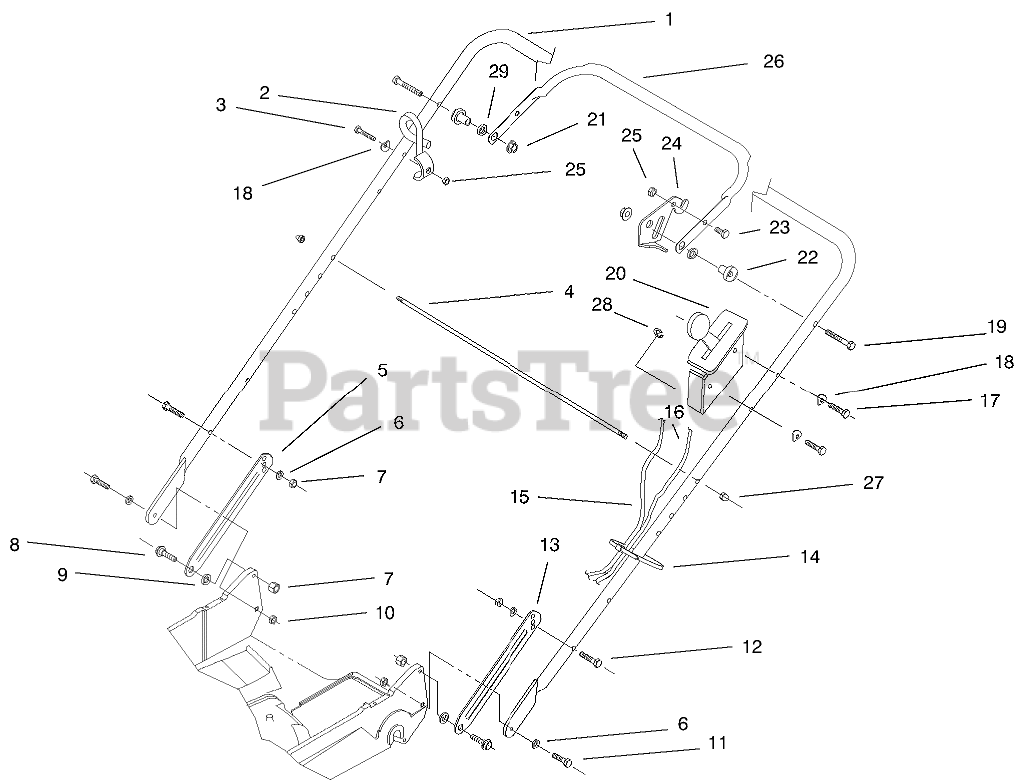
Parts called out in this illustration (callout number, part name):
2	GUIDE-ROPE
3	SCREW-HH
4	ROD-SUPPORT, BAG
5	Latch-Handle
6	WASHER-BELLEVILLE
7	NUT-LOCK, NI
8	SCREW-SHOULDER
9	SPACER
10	NUT-LOCK, NI
11	SCREW-HH
12	SCREW-HH
13	Latch-Handle
14	TIE-CABLE
15	CABLE-BRAKE
16	CABLE-THROTTLE
17	SCREW-HH
18	WASHER
19	SCREW-HH
20	BRACKET-CONTROL, THROTTLE
21	NUT-LOCK, NI
22	SPACER-SUPPORT
23	SCREW-HH
24	LEVER-CONTROL
25	NUT-LOCK, NI
26	BAR-CONTROL
27	NUT-CAP
28	E-RING
29	SPACER-NYLON
